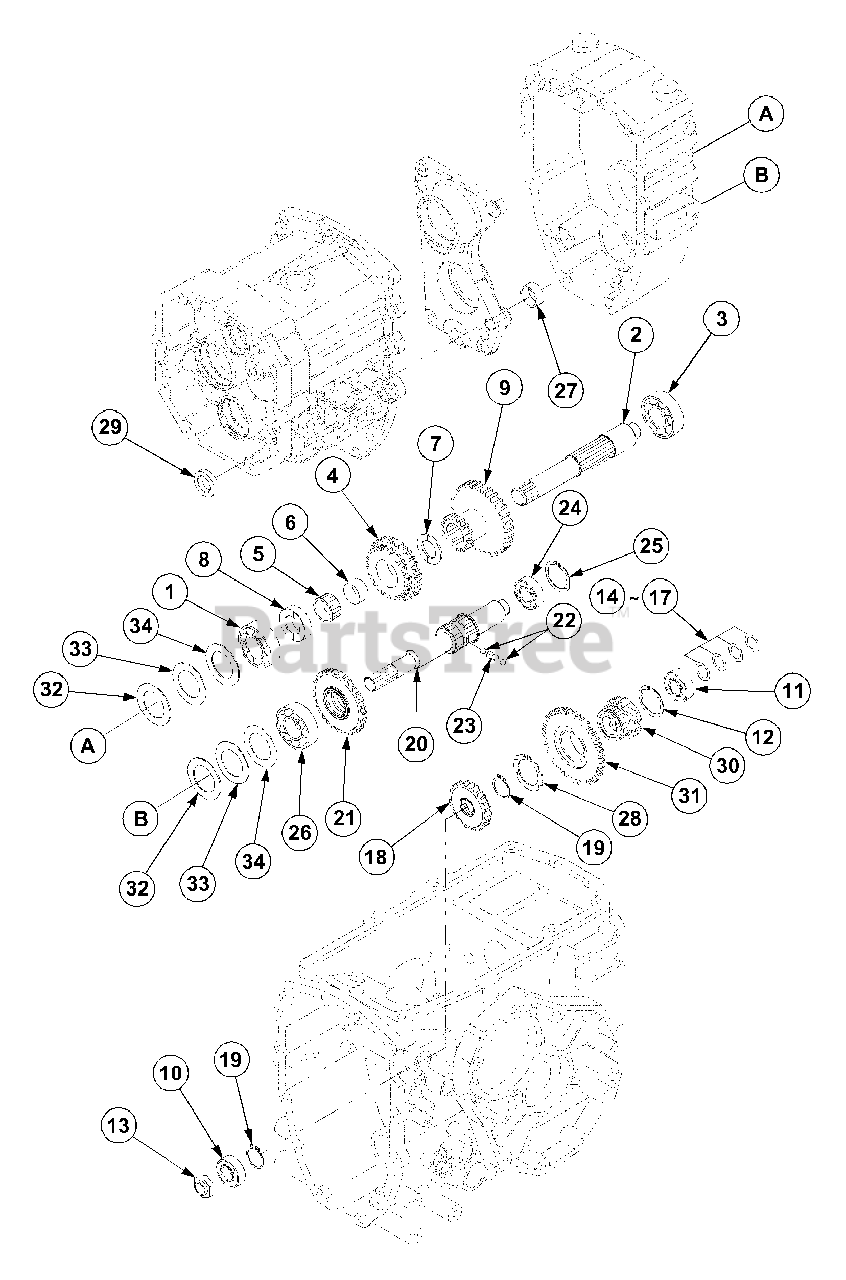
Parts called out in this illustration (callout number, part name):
5	Bearing,Needle
10	Bearing,Taper
11	Bearing,Taper
12	C-Ring
19	C-Ring
25	C-Ring
28	C-Ring
